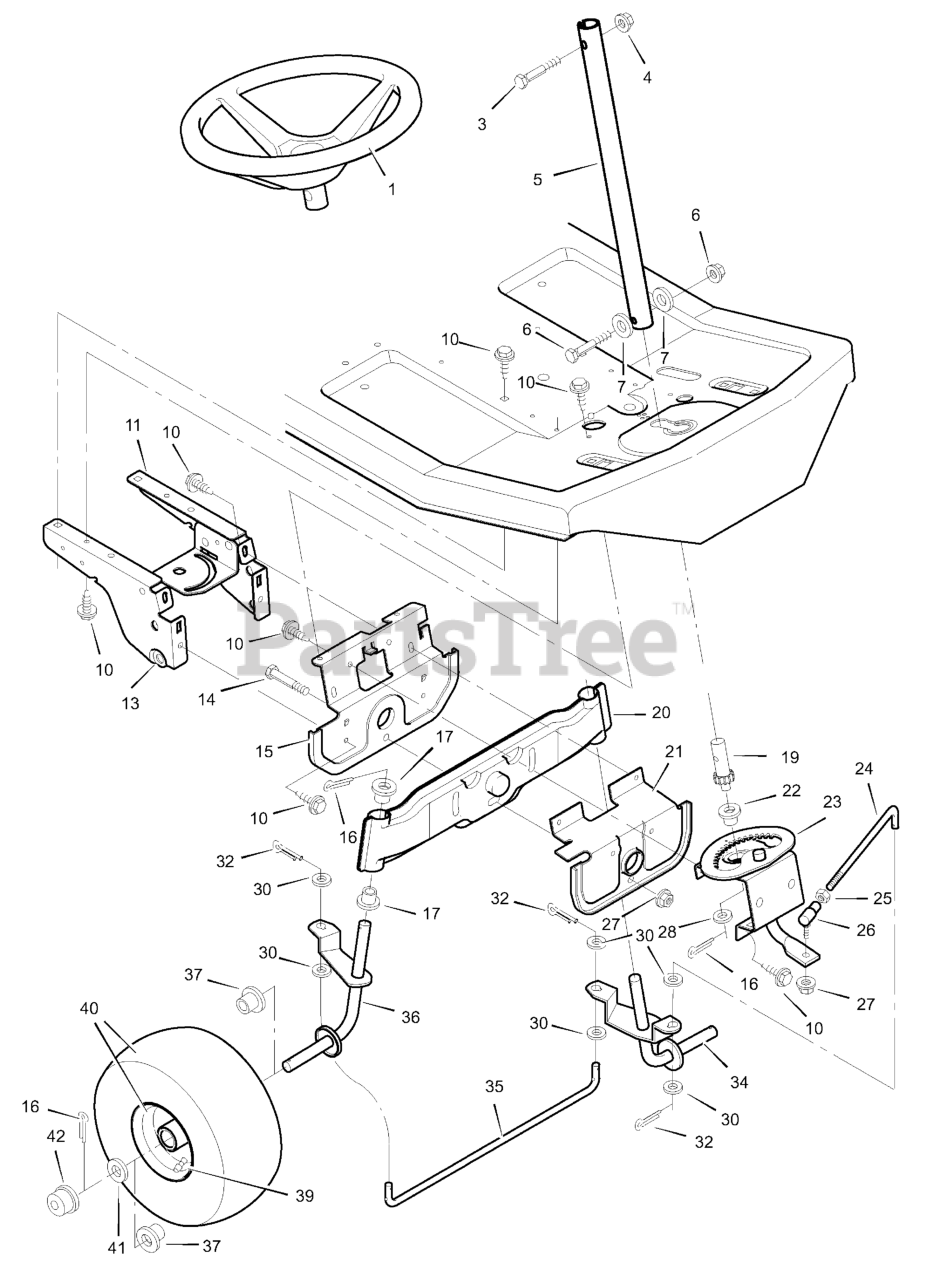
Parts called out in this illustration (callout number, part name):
1	Steering Wheel
3	Bolt, Hex
4	Locknut, Flange
5	Post, Steering
6	Nut, Hex
7	Washer
11	Plate, Left Suspension
13	Plate, Right Suspension
14	Bolt, Hex
15	Support, Front Axle
16	Pin, Cotter
17	Bearing, Spindle
19	Gear, Pinion
20	Axle Assembly, Front
21	Hanger Assembly, Front Axle
22	Bearing
23	Sector Assembly
24	Rod, Drag Link
25	Nut, Hex
26	Ball Joint, Steering
27	Locknut, Flange
32	Pin, Cotter
34	Spindle Assembly, Left
35	Rod, Tie
36	Spindle Assembly, Right
37	Bearing, Wheel
39	Valve Stem
40	Wheel & Tire Assembly
42	Cap, Hub
